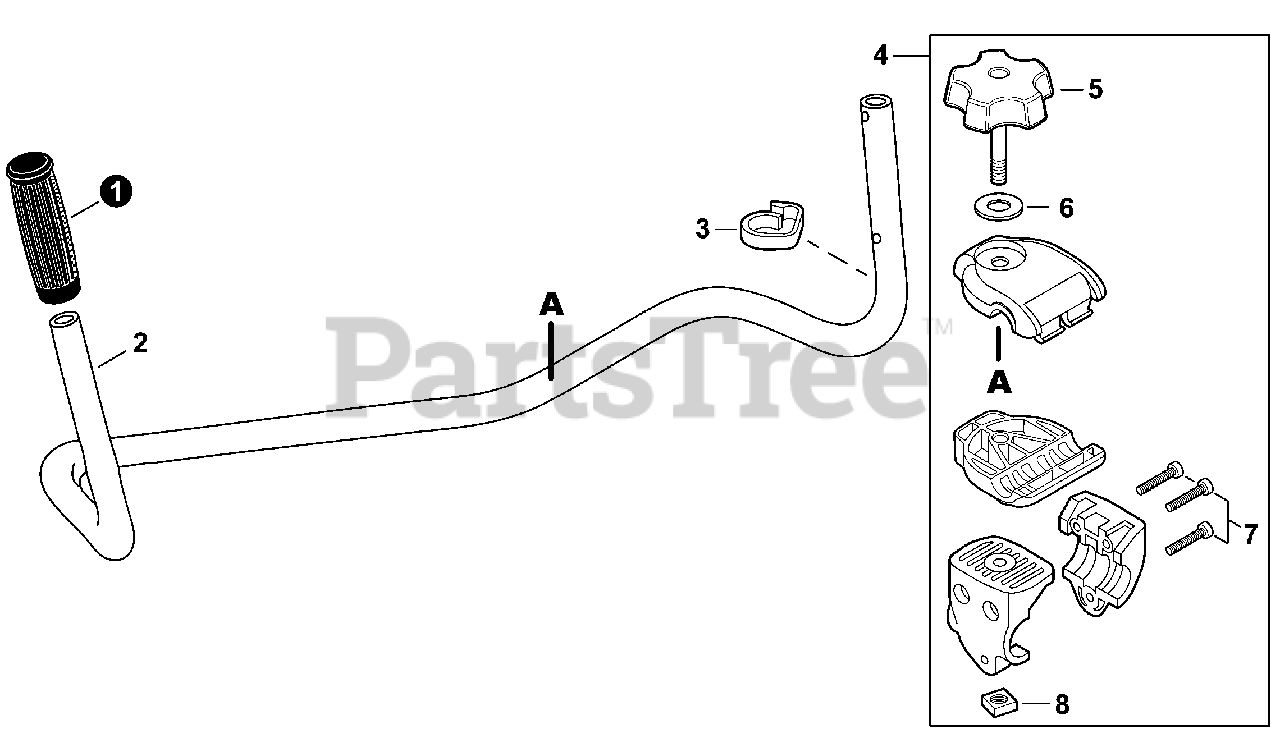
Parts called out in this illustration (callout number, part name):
1	GRIP, HANDLE
2	HANDLEBAR
4	BRACKET KIT, HANDLEBAR
5	KNOB, SCREW M8
6	WASHER 8
7	BOLT, TORX 5×25
8	NUT 8×1.25
